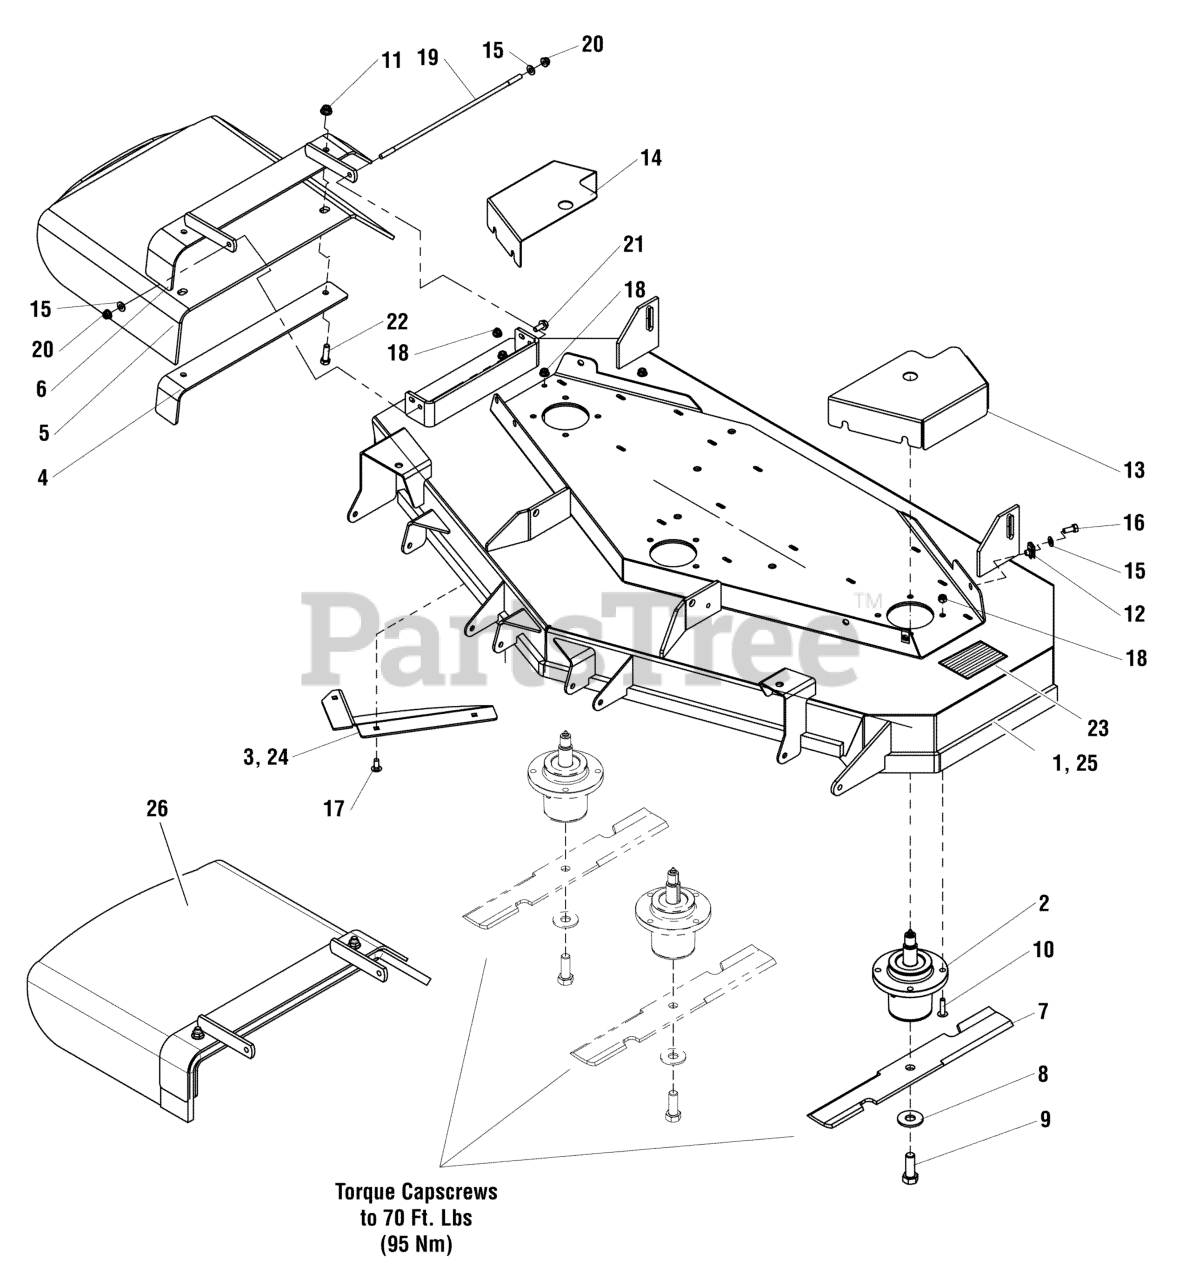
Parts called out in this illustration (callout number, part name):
1	DECK SHELL W/DECALS, 52", SIDE DISCHARGE
2	ASSM, SPINDLE, LOW PROFILE
3	WELD, DISCHARGE BAFFLE, 52" - RED
4	SUPPORT, DISCHARGE CHUTE, 44/48/52 - BLK
5	CHUTE, DISCHARGE, RUBBER, 44/48/52"
6	WELD, MOUNT, DISCHARGE CHUTE - BLK
7	BLADE, 18.0
8	WASHER, 5/8" GRADE 8, YZ
9	BOLT, 5/8-11 X 1-3/4 GR8
10	BOLT, 5/16-18 X 1-1/4" FLANGE
11	NUT, 3/8-16 HEX NYLOCK FLANGE
12	BODY CLIP, 5/16-18-7GA MATERIAL
13	GUARD, 52" DECK, IS2000, LH - RED
14	GUARD, 52" DECK, IS2000, RH - RED
15	WASHER, 5/16" SAE
16	BOLT, 5/16-18 X 3/4 GD5
17	CARRIAGE BOLT, 5/16-18 X 3/4
18	NUT, 5/16-18 HEX NYLOCK FLANGE
19	ROD, BRAKE LINKAGE
20	NUT, 5/16-24 HEX NYLON LOCK
21	BOLT, 5/16-18 X 3/4 GD5
22	BOLT, 3/8-16 X 1-1/4" GD5 CZ
23	SAFETY WALK, 4.00 X 7.50
24	PLATE, DEFLECTOR, 52" - BLK
25	DECK SHELL W/DECALS, 52" SIDE DISCHARGE
26	KIT, DISCHARGE CHUTE, 44/48/52
